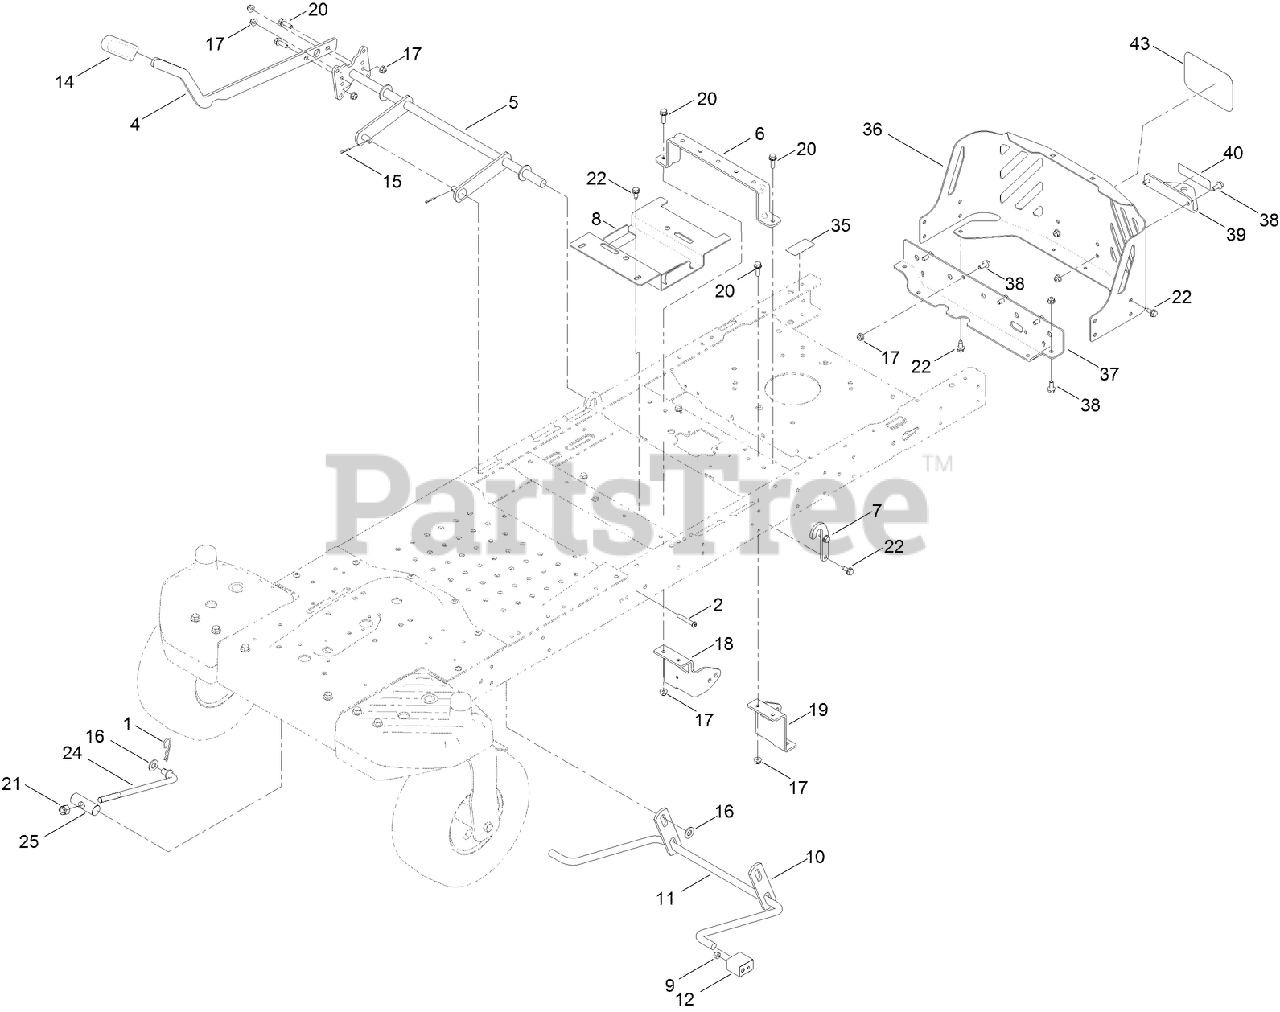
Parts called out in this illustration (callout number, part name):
1	PIN-COTTER
2	SCREW-HSBH
4	LEVER-LIFT
5	LIFT-DECK, WIDE
6	BRACE-SEAT, REAR
7	BRACKET-LIFT
8	BRACKET-BATTERY
9	NUT-LOCK, NI
10	LINK-LIFT
11	ARM-LIFT, REAR (WIDE)
12	BLOCK-PIVOT
14	GRIP-LEVER
15	PIN-COTTER
16	WASHER-FLAT
17	NUT-HF, NI
18	MOUNT-HYDRO, FRONT (RH)
19	MOUNT-HYDRO, FRONT (LH)
20	SCREW-HHF
21	NUT-HEX
22	SCREW-HWHTF
24	ROD-MOUNT, DECK
25	PIN-PIVOT
35	DECAL-BYPASS
36	GUARD-ENGINE, WIDE
37	CROSSMEMBER-REAR, WIDE
38	SCREW-HHF
39	BRACKET-HITCH
43	DECAL
